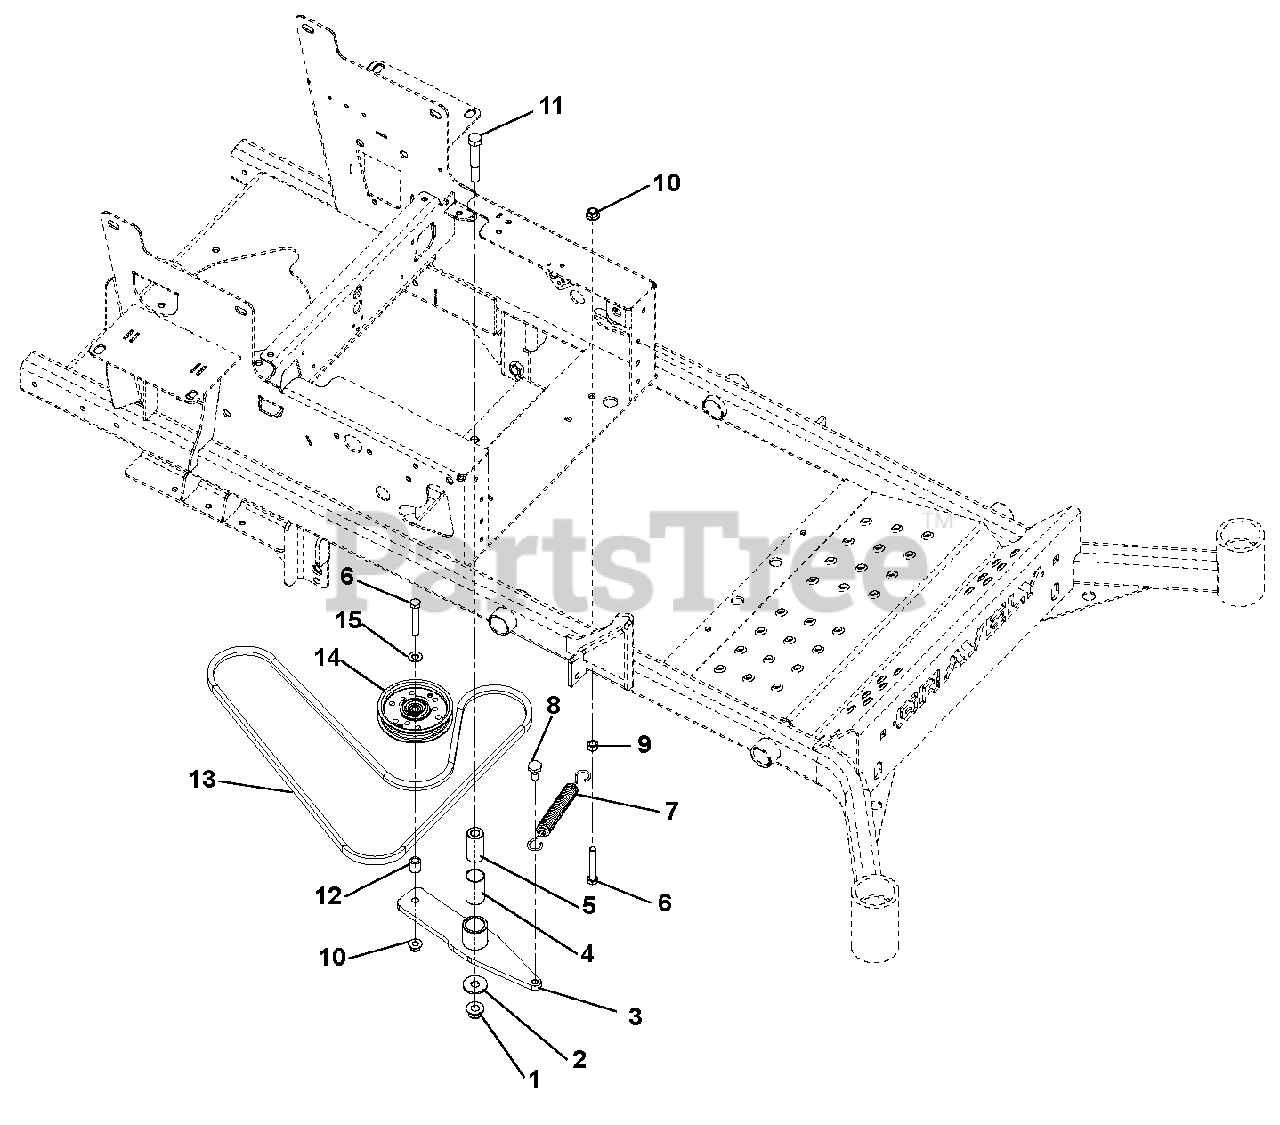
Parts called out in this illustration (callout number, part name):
1	Nut, Nyloc Flange .50-13
2	Washer, Flat Steel .511 x 1.441 x .125
3	Weldment, Hydro Drive Idler Arm
4	Bushing, 1.00 x 1.125 x 1.936
5	Bushing, Spacer .505/.500 x .999/.996 x 2.05/2.03 Promaster
6	Bolt, Hex .38-16 x 2.50
7	Spring, Extension
8	Bolt, Shoulder EP .38-16 x .30 Hex
9	Nut, Hex .38-16
10	Nut, Nyloc Flange .38-16
11	Bolt, Hex .50-13 x 3.25
12	Bushing, Sleeve .407 x .625 x .750
13	Belt, A 69.26 Raw Cogged
14	Idler, Flat 4.00 x .38
15	Washer, Flat Steel .406 x .812 x .065
